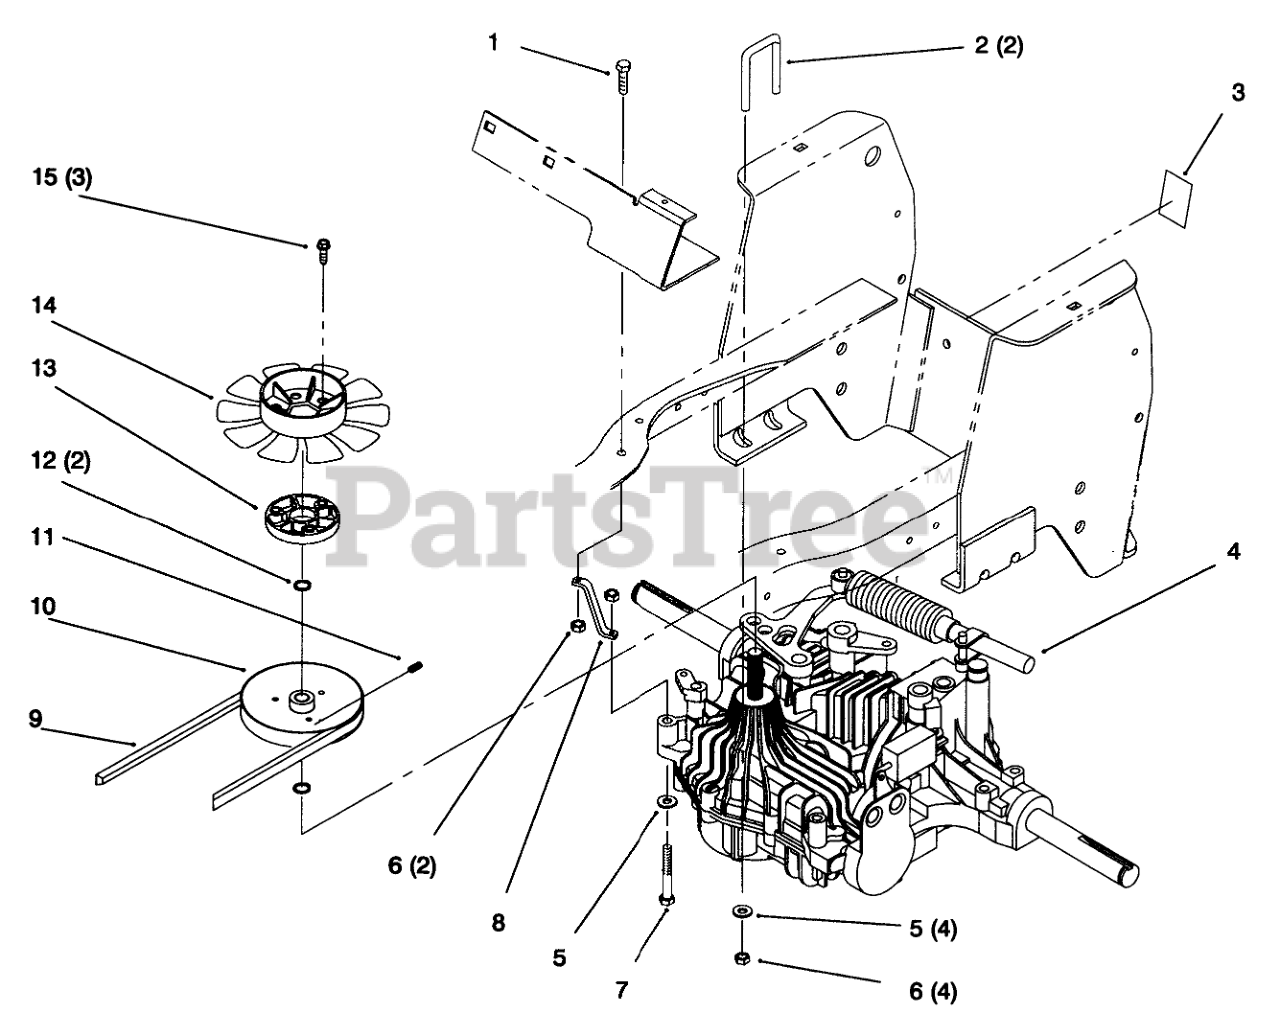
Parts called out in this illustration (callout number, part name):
1	SCREW-HH
2	U-BOLT
3	Decal-Hydro Valve (Only On: 72046)
3	Decal-Bypass (Only On: 72064)
4	TRANSAXLE - HYDROSTATIC
5	WASHER-PLAIN
6	NUT-LOCK, NI
7	SCREW-HH
8	STRAP-TRQ HY
9	Belt-Hydro
10	PULLEY-HYDRO TRANS
11	SCREW-HSH
12	SNAP RING
13	SPACER - FAN
14	FAN - HYDRO
15	SCREW-HWHTF
